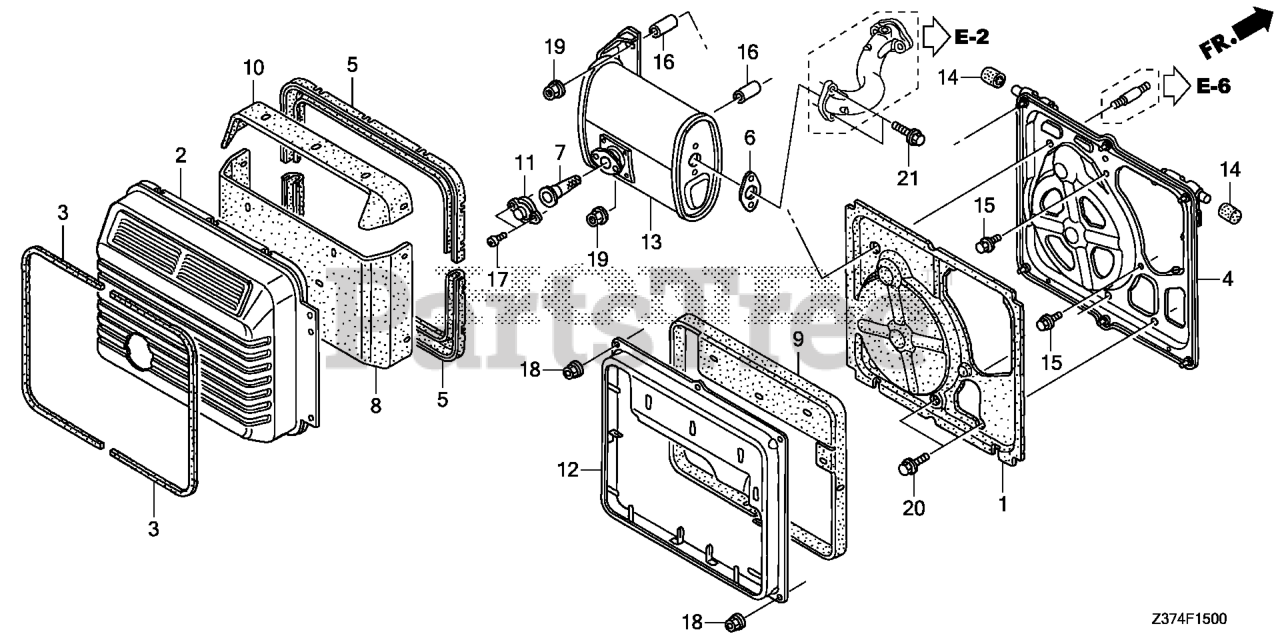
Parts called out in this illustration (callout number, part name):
1	SEPARATOR, MUFFLER (INNER)
2	PROTECTOR, MUFFLER (OUTER) *NH105* (MAT BLACK)
3	SEAL (10X5X785)
4	PROTECTOR, MUFFLER (INNER)
5	SEAL, MUFFLER PROTECTOR
6	GASKET, EX. PIPE
7	ARRESTER, SPARK
8	INSULATOR, MUFFLER PROTECTOR (A)
9	INSULATOR, MUFFLER PROTECTOR (B)
10	INSULATOR, MUFFLER PROTECTOR (C)
11	PIPE, EX. TAIL
12	GUIDE, EX. AIR
13	MUFFLER
13	MUFFLER COMP
14	RUBBER, STOPPER
15	BOLT, FLANGE (6X12) (CT200)
16	COLLAR, MUFFLER
17	SCREW, PAN (5X16)
18	NUT, FLANGE (6MM)
19	NUT, FLANGE (8MM)
20	BOLT, FLANGE (8X16)
21	BOLT, FLANGE (8X40)
